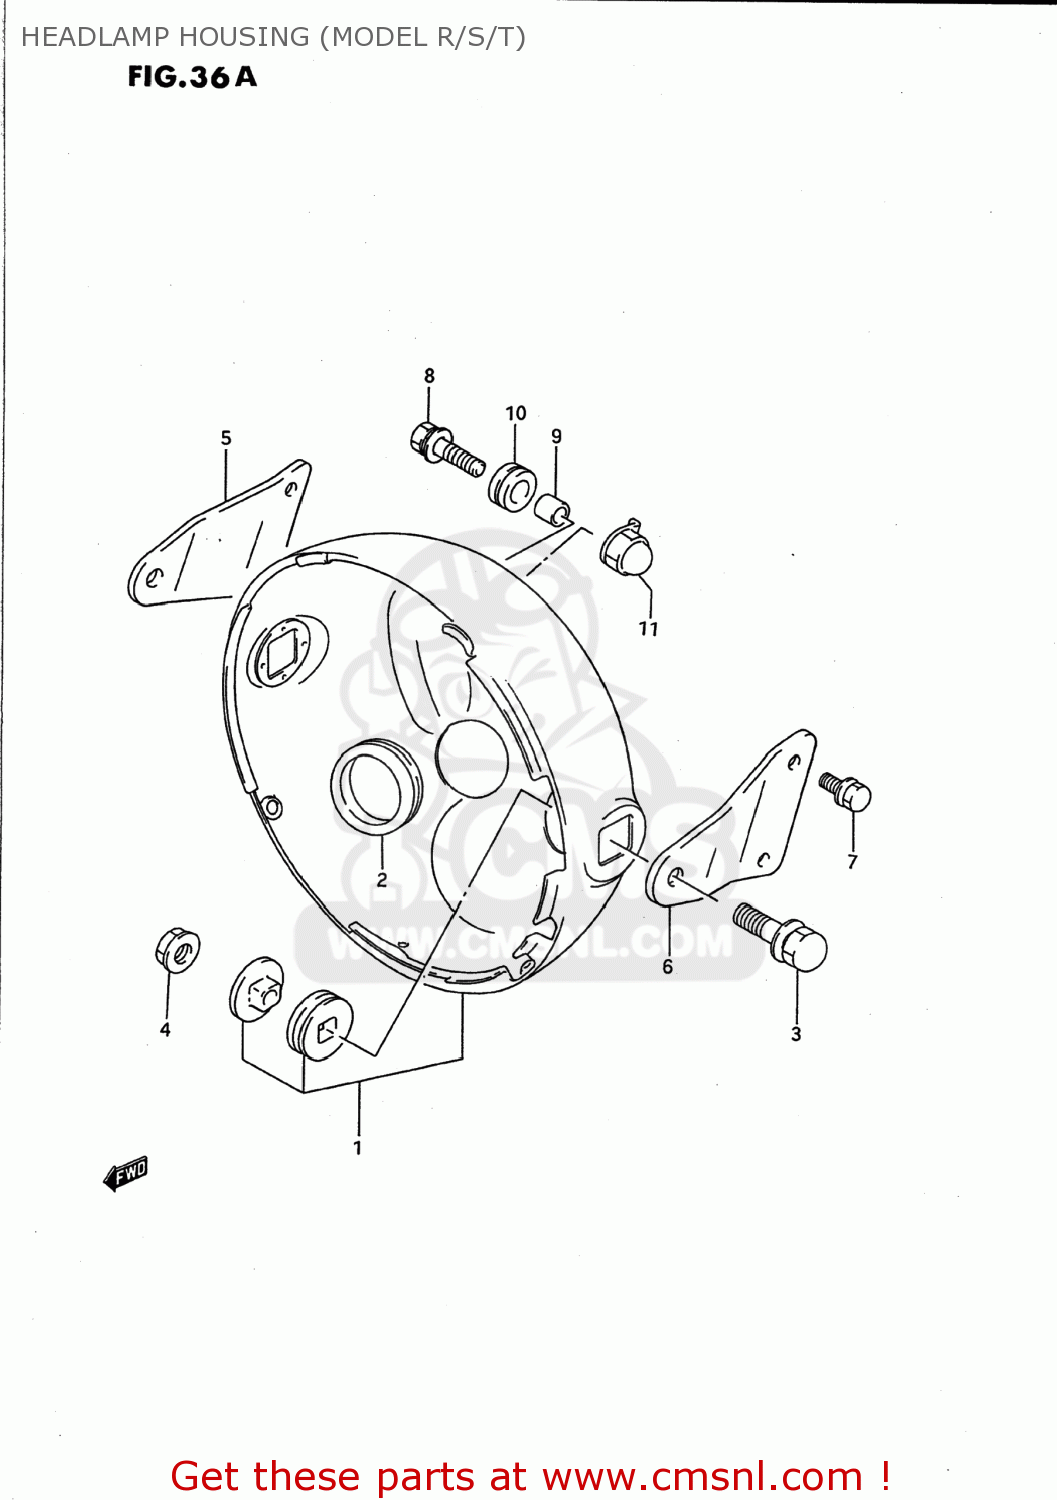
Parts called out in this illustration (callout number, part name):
1	HOUSING,HEADLAMP
2	GROMMET
3	BOLT
4	NUT
5	STAY,HEADLAMP HOUSING,R
6	STAY,HEADLAMP HOUSING,L
7	BOLT
8	BOLT
9	SPACER(6.5X10.5X12)
10	CUSHION
11	PLATE,HEADLAMP
